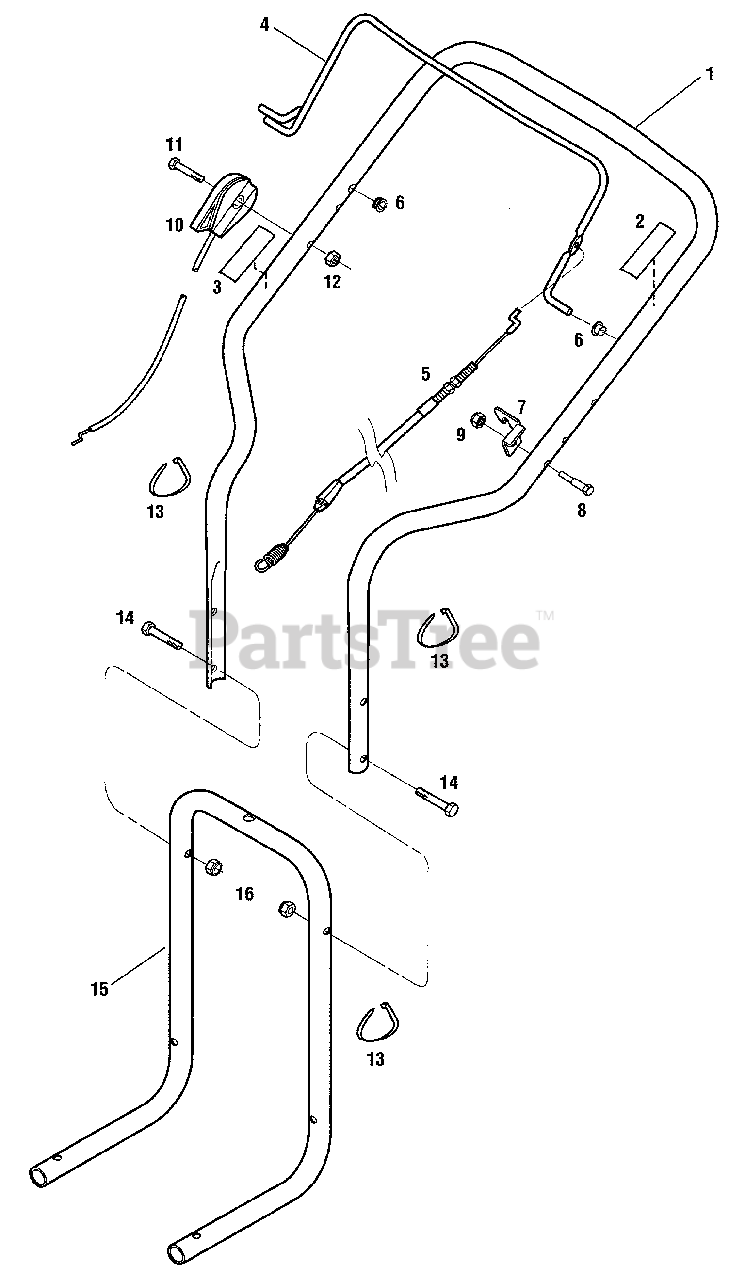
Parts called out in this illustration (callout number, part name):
1	Upper Handlebar
2	Decal-Bail Engage/Disengage
3	Decal-Throttle
4	Control Bail-Trimmer Head
5	Cable Assembly-Trimmer Head
7	Cable Bracket
8	Hex Hd. Screw, 1/4-20 x 1-1/8
9	Hex Flange Lock Nut, 1/4-20
10	Throttle Lever & Cable Assembly
11	Hex Hd. Screw, 1/4-20 x 2
12	Hex Lock Nut, 1/4-20
13	Cable Tie
14	Hex Hd. Screw, 5/16-18 x 1-1/2
15	Lower Handlebar
16	Hex Lock Nut, 5/16-18
